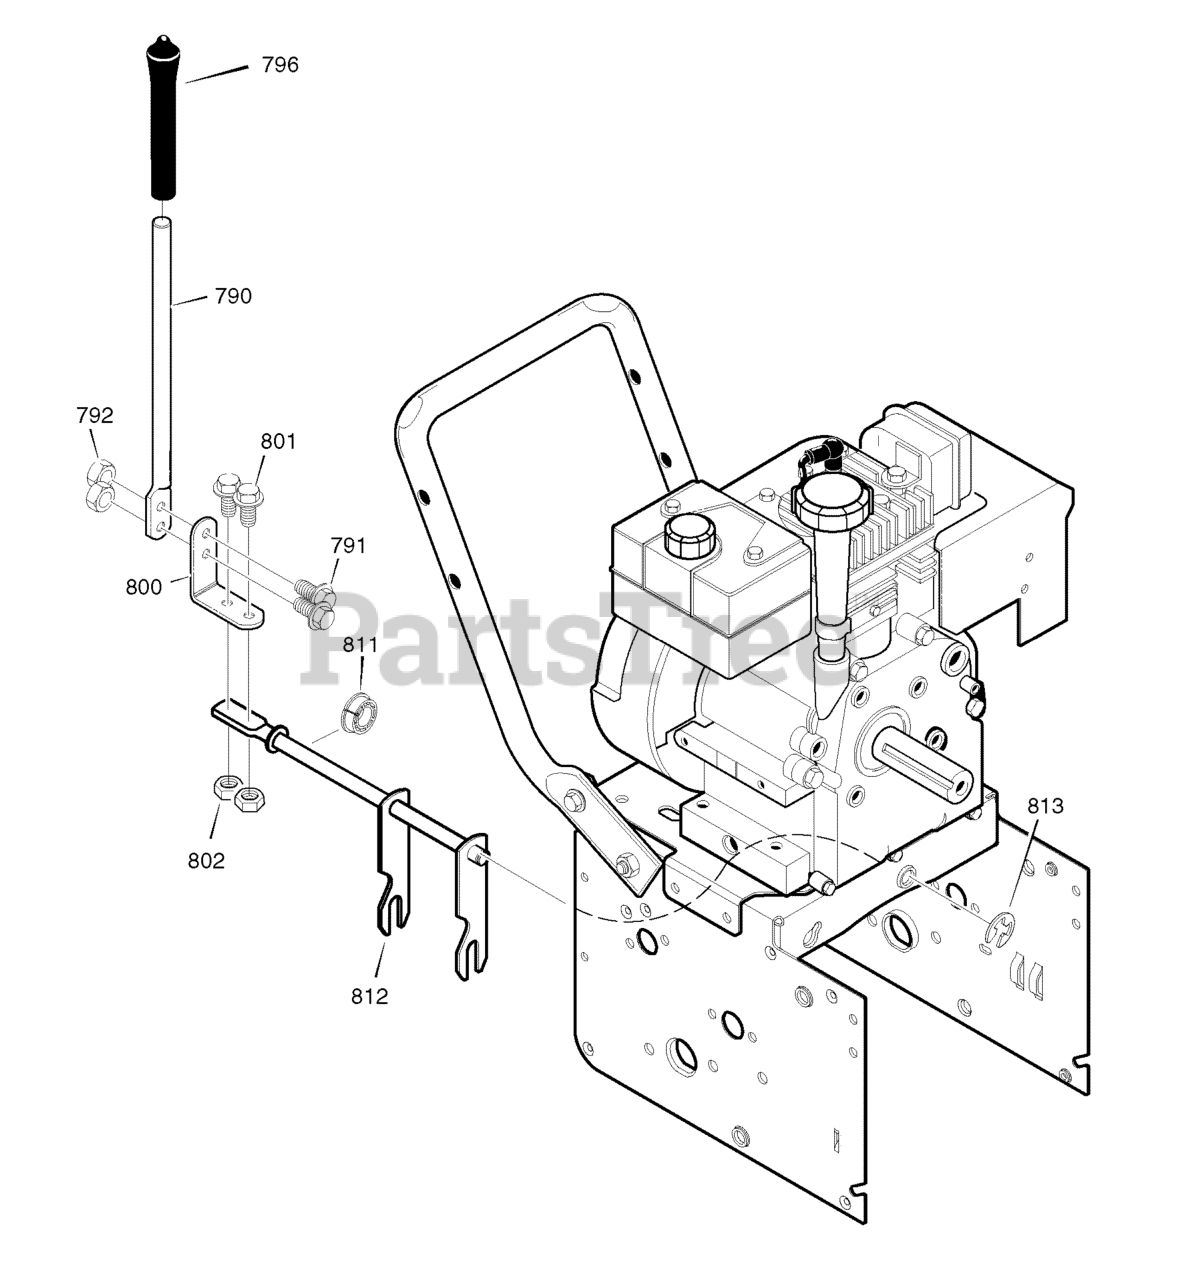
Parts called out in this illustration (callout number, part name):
790	ROD, SHIFT
791	SCREW, 1/4-20X.75
792	NUT, 1/4-20
796	KNOB, SLIP
800	LEVER, SPRING
801	SCREW, 1/4-20X.75
802	NUT, 1/4-20
811	BEARING, FLANGED
812	ROD ASSY., SPEED SELECT
813	RETAINER, RING
